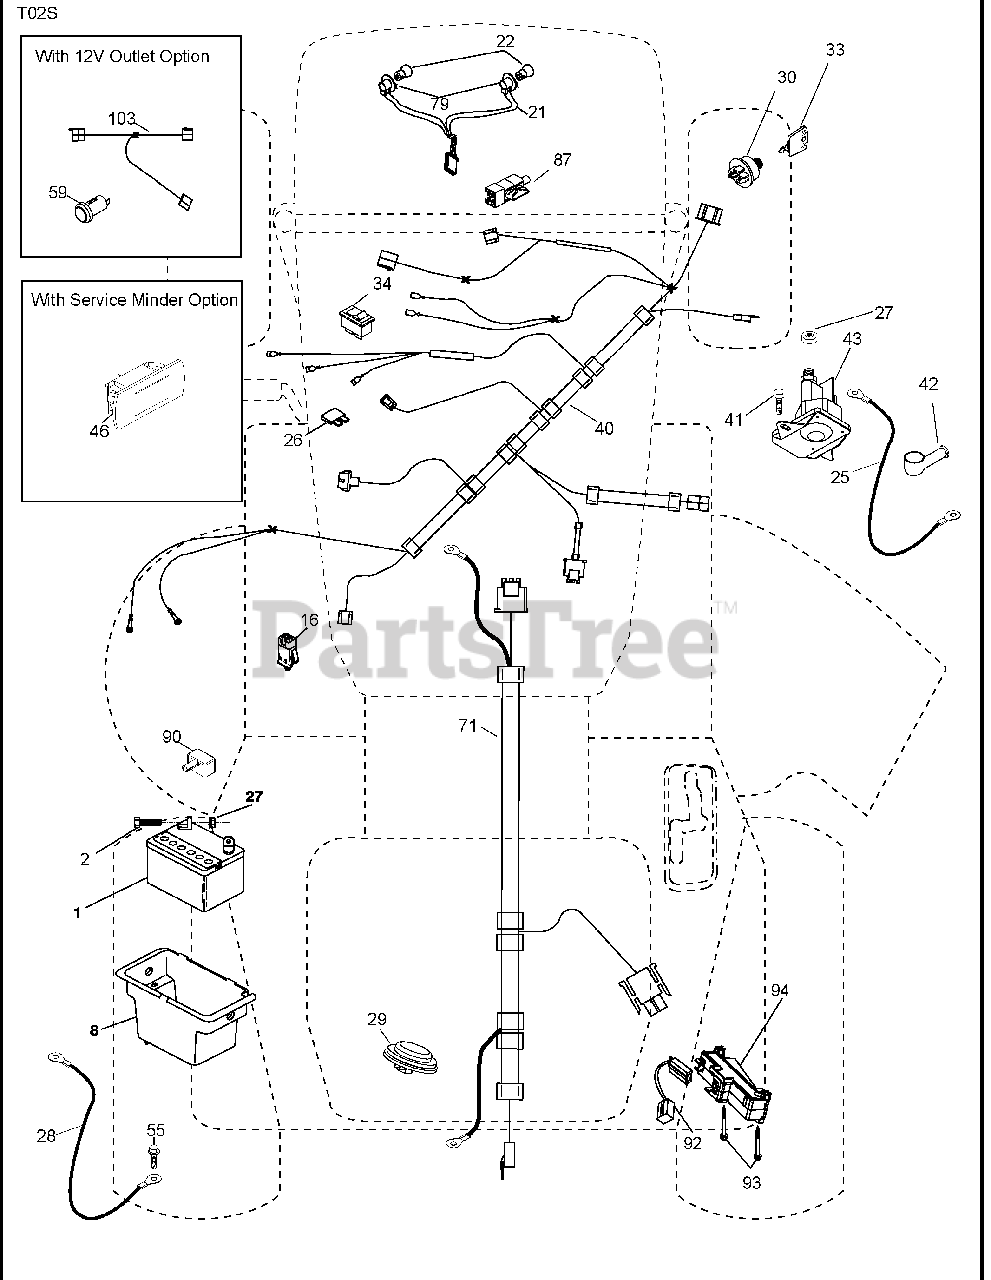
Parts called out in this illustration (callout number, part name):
1	Battery
2	Bolt Hex Hd 1/4-20 unc x 3/4
8	Box Battery
16	Switch Interlock
21	Harness Socket Light
22	Bulb, Light # 1156
25	Cable Battery 6 Ga. Red 14.5
26	Fuse
27	Nut Keps Hex 1/4-20 unc
28	Cable Ground 18" Rear Battery Blk 6 Ga.
29	Switch Seat
30	Switch Ign
33	Key Ign Molded Generic
34	Switch Light/Reset
40	Harness Ign
41	Screw 1/4-20 unc x 1/2
42	Cover Terminal Red
43	Solenoid
55	Screw 5/16-18 x 3/4
71	Harness Ign. Chass.
79	Socket Asm Bulb Twistlock
87	Switch interlock Clutch Cable
90	Cover Terminal
92	Harness Pigtail Reverse Switch
93	Screw Plastic 10-14 x 2.0
94	Modual Reverse ROS
